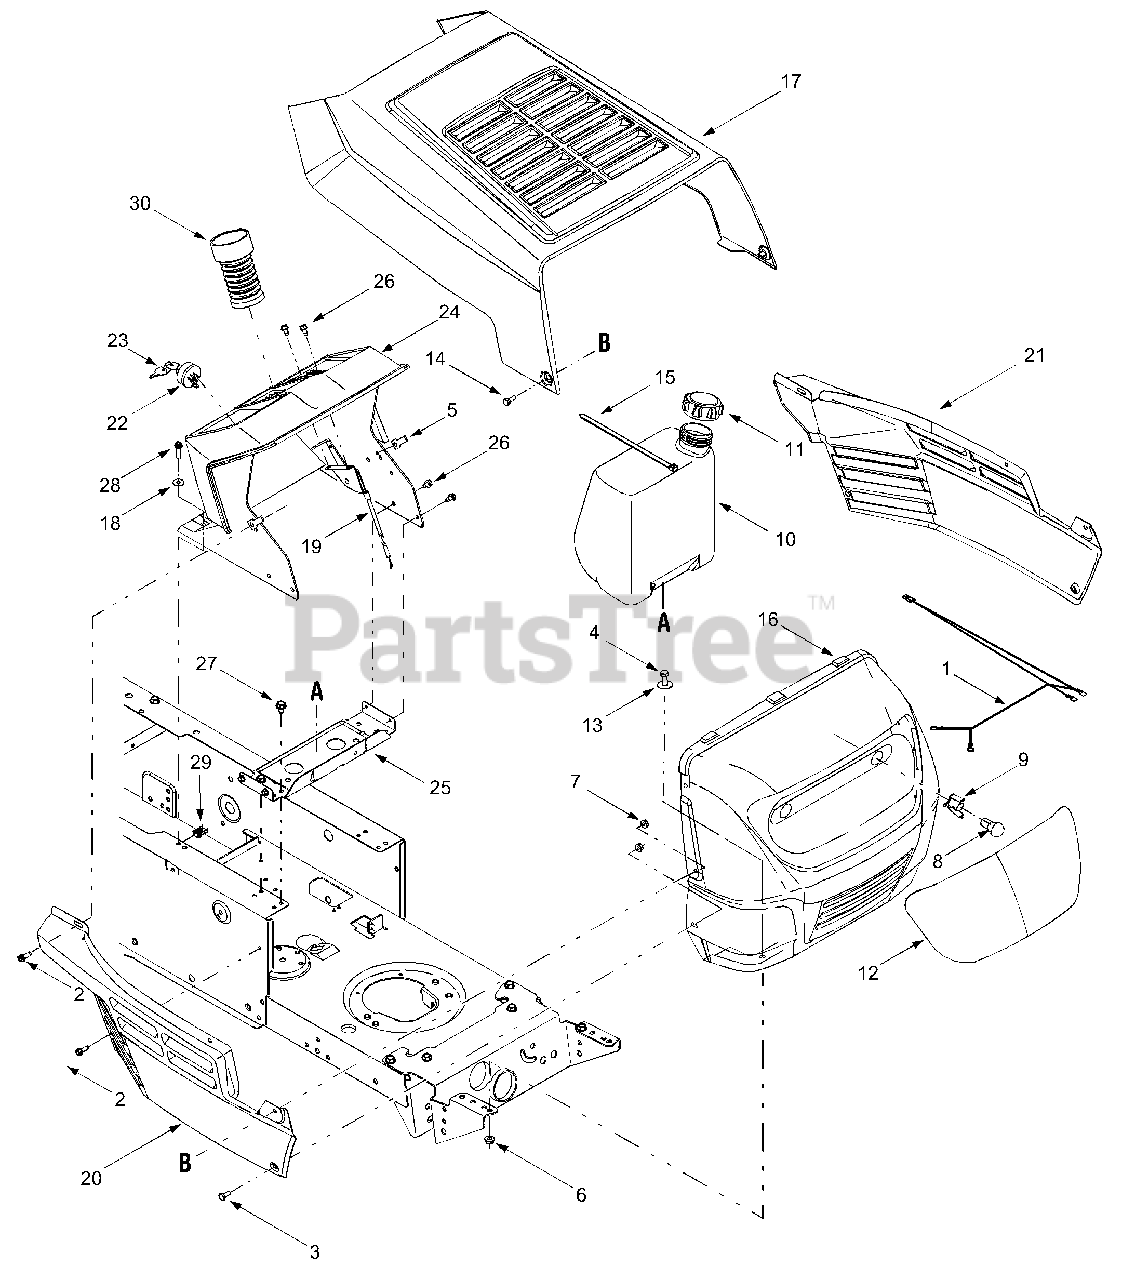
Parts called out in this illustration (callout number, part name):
1	Headlamp Harness Assembly
2	Self-tapping Screw, 1/4-20 x .75
3	Hex Screw, 1/4-20 x .620
4	Hex Screw, 5/16-18 x .75
5	U-type Speed Nut, 1/4-20
6	Flange Lock Nut, 5/16-18
7	Flange Lock Nut, 1/4-20
8	Headlamp, 12V
9	Headlamp Socket
10	Fuel Tank, 1.5 gal.
11	Fuel Tank Cap
12	Lens
13	Flat Washer, .344 x 1.0 x .063
14	Shoulder Screw, 1/4-20 x .375 /.125
15	Cable Tie, 30.66
19	Throttle / Choke Control, 18.5"
23	Keys (pair)
24	Dash Panel
25	Battery Support Bracket
26	Self-tapping Screw, 1/4-20 x .5
27	Self-tapping Screw, 5/16-18 x .5
28	Self-tapping Screw, 1/4-20 x 1.0
29	U-type Speed Nut, 1/4-20
30	Steering Bellow, 4.75"
